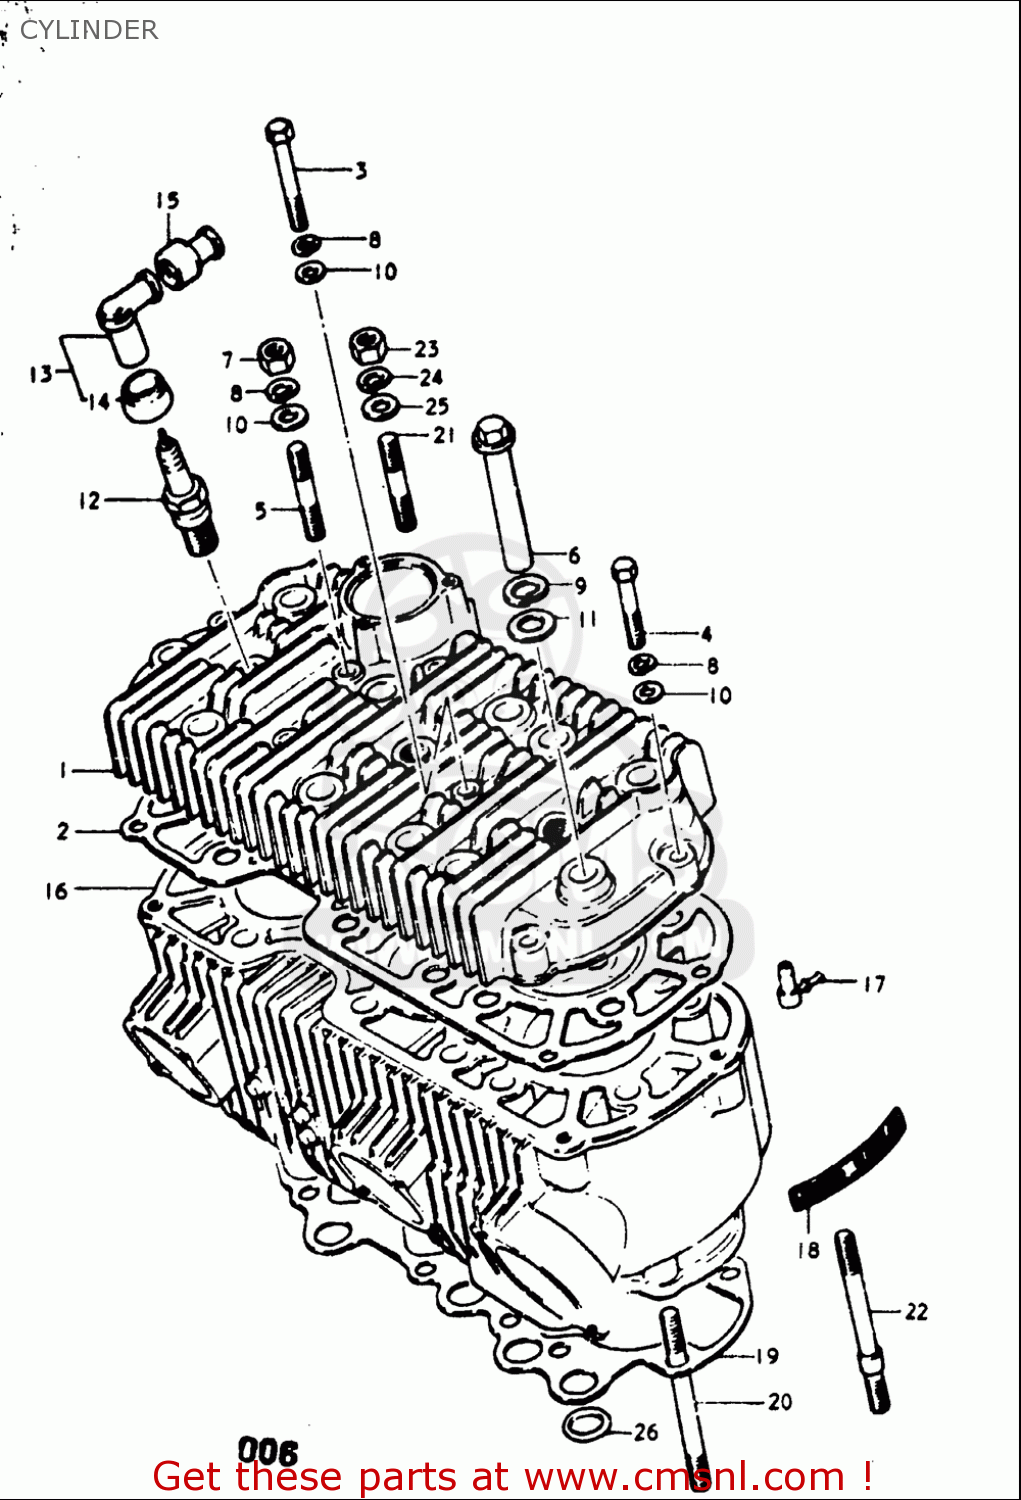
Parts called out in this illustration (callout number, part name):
2	GASKET,CYLINDER HEAD (NAS)
3	BOLT
4	BOLT
6	NUT
7	NUT
8	WASHER,LOCK
9	WASHER,LOCK
10	WASHER
11	GASKET(14X26X3) (NAS)
12	PLUG,SPARK
13	CAP,SPARK PLUG
15	SEAL,HIGH TENSION CORD
17	UNION,OIL HOSE
18	EMBLEM,CYLINDER
19	GASKET,CYLINDER (NAS)
21	BOLT
22	STUD
23	NUT
24	WASHER,LOCK
25	WASHER
26	O RING(D:2.4,ID:21.8)
